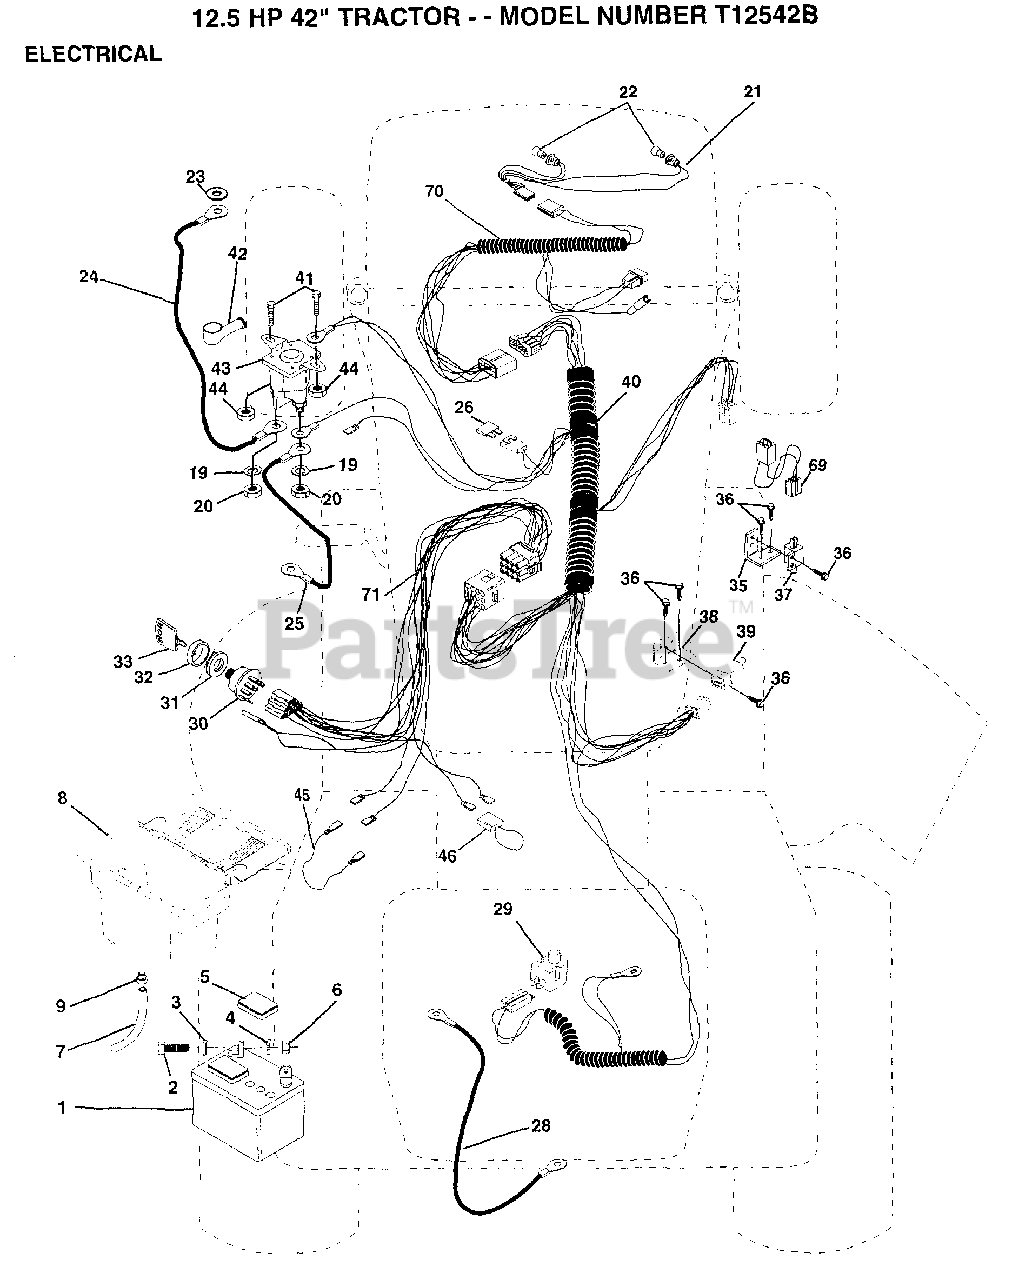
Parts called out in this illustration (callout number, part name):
2	BOLT LT
3	WASHER
4	LOCKWASHER
5	"CAP,BATTERY "
7	TUBE T
9	HOSE CLAMP T
20	NUT
21	"HARNESS,LIGHT SOC"
22	HEADLAMP BULB
23	LOCKWASHER
24	"CABLE T, BATTERY"
26	FUSE HYT
28	CABLE T
29	SWITCH SEAT
30	SWITCH IGN 4POS
31	NUT IGNITION
32	COVER KEY SWITCH
33	KEY
35	BRACKET LT
36	SCREW
37	SWITCH-INTER. GT
38	BRACKET SWITCH IN
39	SWITCH INTERLOCKT
40	HARNESS IGN B&S
41	BOLT HXHD FIN
44	NUT HXKEP 1/4X20
45	ADAPTER AMMETER
46	PROTECTION LOOP
69	ADAPTER.HARN.SERV
70	HARNESS.ENGINE
71	HARNESS DASH LT
